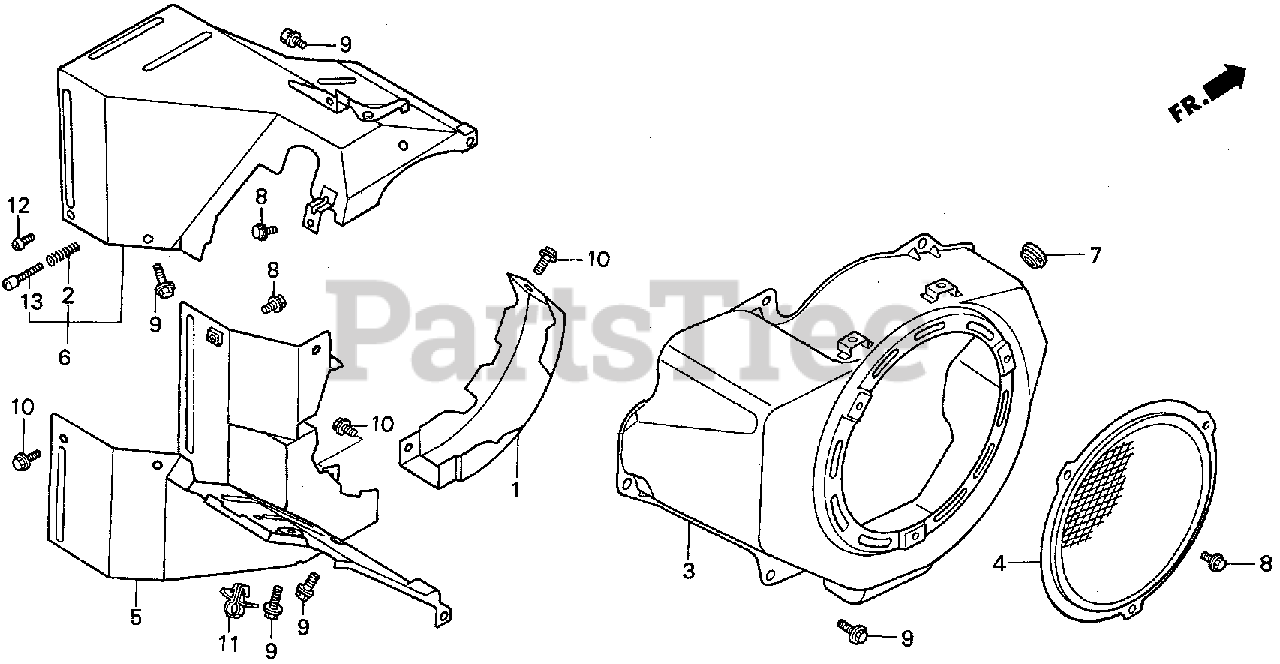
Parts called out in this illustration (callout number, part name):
1	SCROLL, ALTERNATOR FAN
2	SPRING, CONTROL ADJUSTING
3	COVER, FAN
4	PROTECTOR, FAN COVER
5	SHROUD (LOWER)
6	SHROUD ASSY. (UPPER)
7	GROMMET, DRAIN HOLE
8	BOLT, FLANGE (6X8)
9	BOLT, FLANGE (6X12) (CT200)
10	BOLT, FLANGE (5X10)
11	CLIP, WIRE HARNESS (6MM) (WHITE)
12	SCREW, PAN (5X8)
13	SCREW, PAN (5X32)
